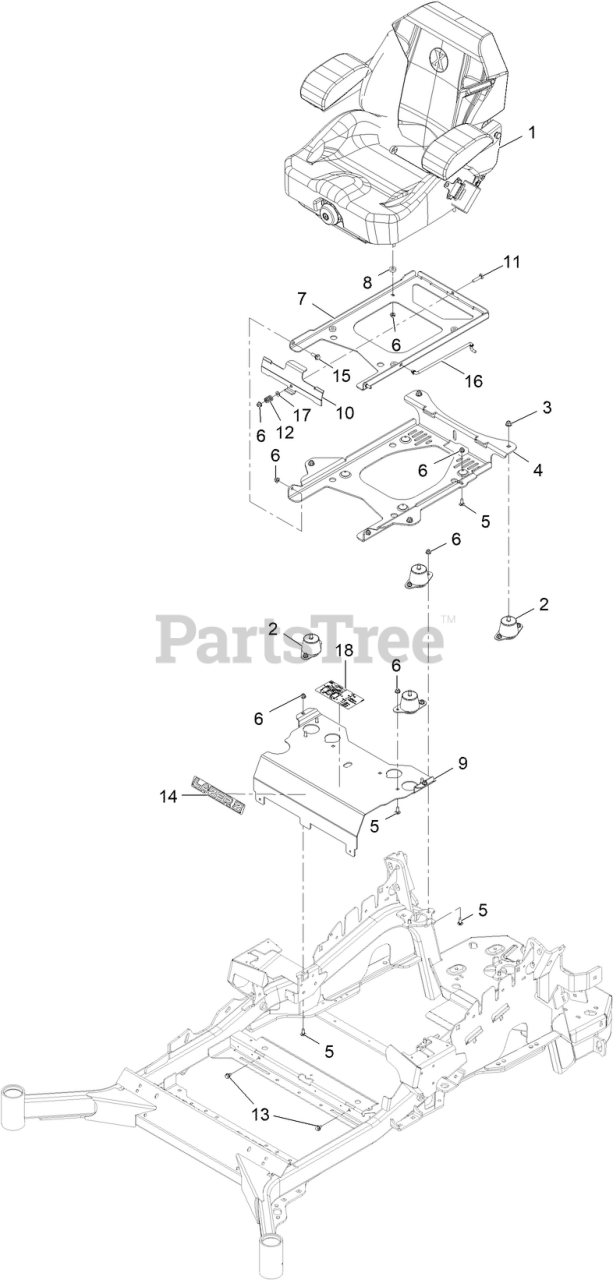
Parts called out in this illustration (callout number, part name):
1	KIT-SUSPENSION SEAT
2	ISOLATOR-SEAT
3	NUT-HF, NI
4	PLATE-TILT, SEAT SUPPORT
5	SCREW-CARR
6	NUT-HF, NI
7	PLATE-FRAME, SEAT
9	Panel-Front, Seat Mount
10	PLATE-LATCH, SEAT
11	BOLT-CARR
12	SPRING-COMPRESSION
13	Screw-HWH 5/16-18 X 3/4 Tf
14	DECAL, LAZER MODEL
15	SCREW-SHOULDER
16	ROD-PROP
17	WASHER-PLAIN
18	DECAL-LAZER 96 SERVICE AID
